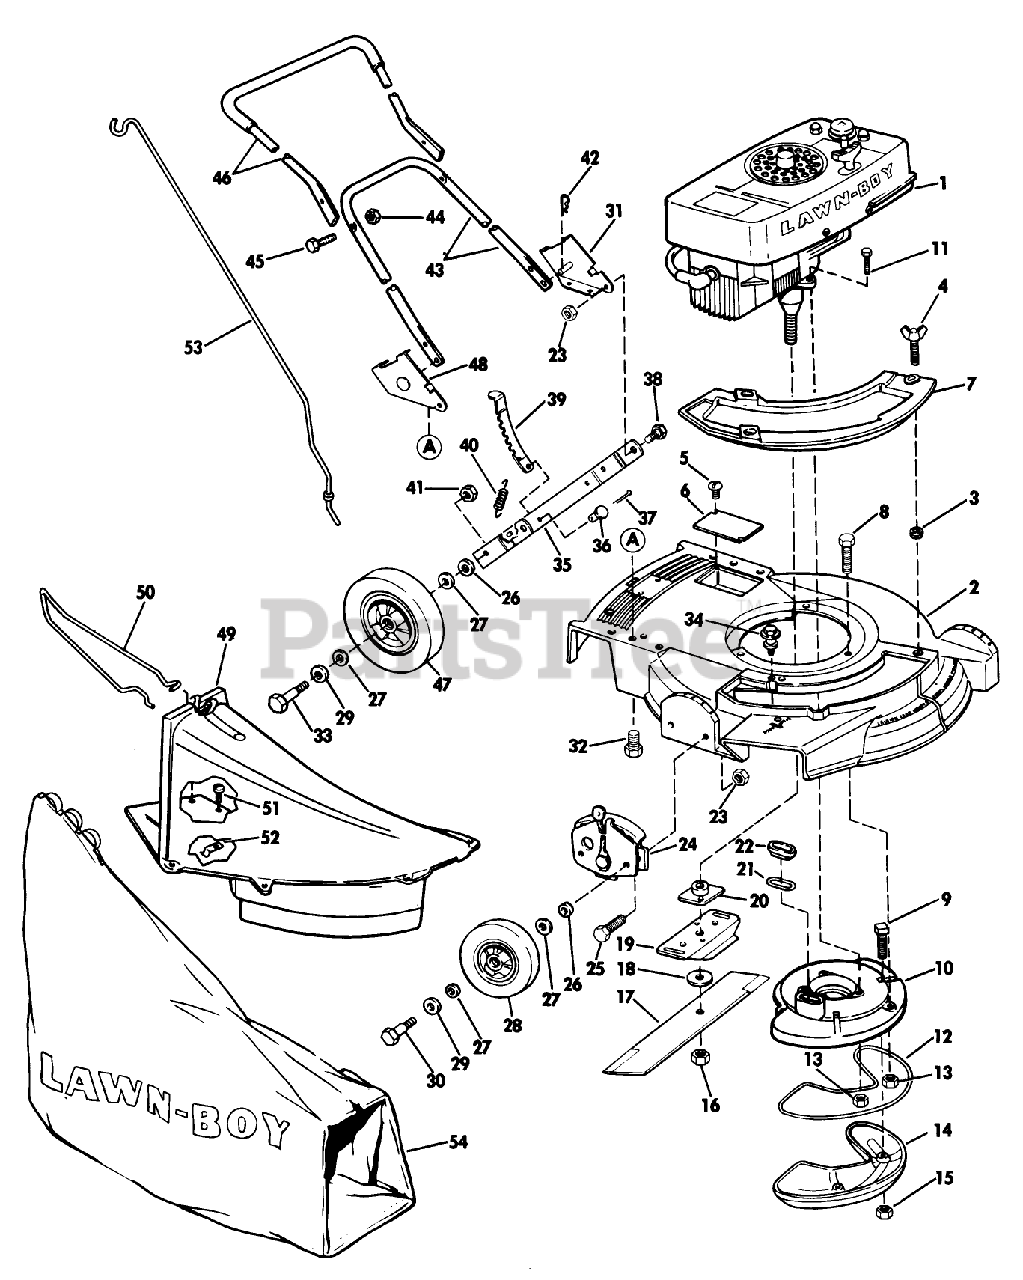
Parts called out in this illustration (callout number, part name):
4	WING SCREW LAWRE
15	LOCKNUT E
16	NUT-BLADE
20	PLATE AND COLLAR ASM
21	GASKET S
26	WASHER WROUGHT
28	WHEEL & TIRE KIT
30	BOLT WHEEL
38	BOLT-SHOULDER
40	SPRING N.A.S
41	LOCKNUT
42	HAIR PIN
44	Nut-Handle
46	Handle-Top (Model 5081 Only)
53	ROD GRASSBAG
